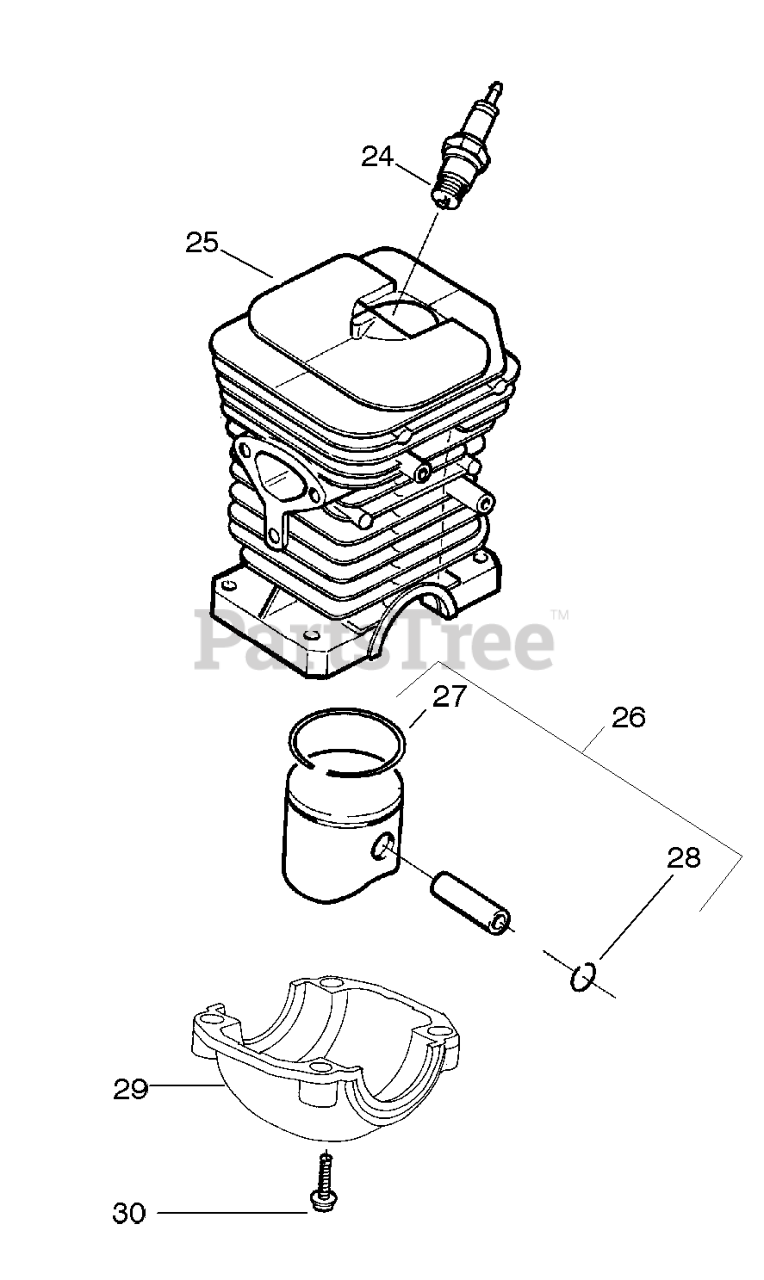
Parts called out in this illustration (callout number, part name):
24	Spark Plug
25	CYLINDER ASSY/141
26	KIT-PISTON
27	PISTON RING HV41
28	C-CLIP,PSTN PIN 36/41
29	CAP-CRANKSHAFT
30	SCREW-M5-0.8 X 25MM(TAP)
